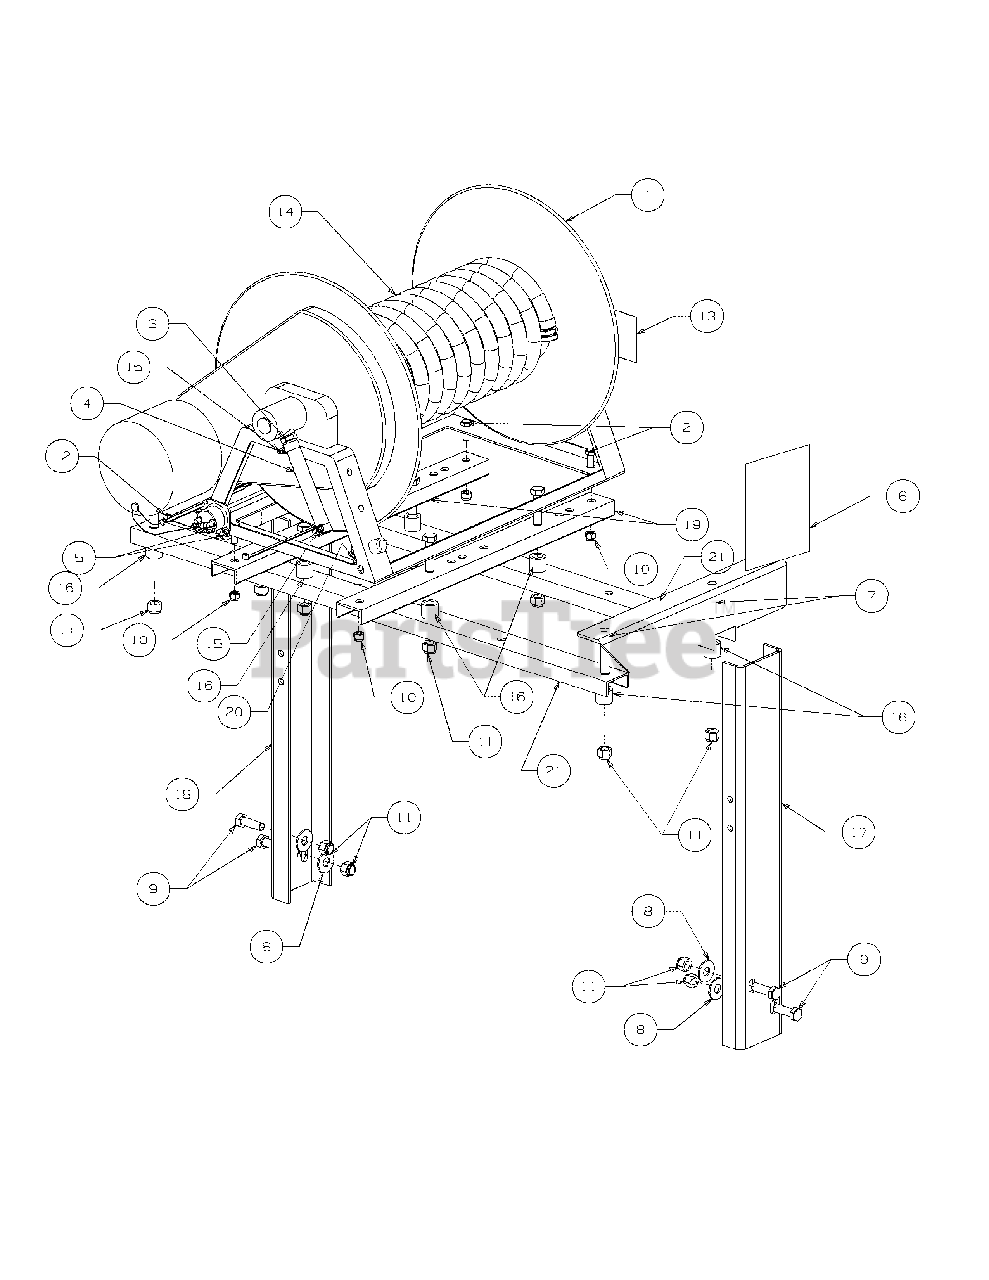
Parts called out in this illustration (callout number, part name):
2	Capscrew, 3/8-16 x 1
3	1/2 Hose Barb, 1/2 (M) NPT
4	1/2" Hose by the foot
5	Ring Terminal, 3/8"
6	Electric Wiring Kit
7	Cap Screw, 1/2-13 x 2 Hex Hd
8	Flat Washer, 1/2 USS
9	Cap Screw, 1/2-13 x 1-1/2 Hex Hd
10	Lock Nut, Nylon Insert, 3/8-16
11	Lock Nut, Nylon Insert, 1/2-13
12	Cable Tie
13	Decal, Maximum Hose Length
14	Hose Assembly, 800 PSI, 1/2" x 300'
15	Hose Clamp, 1/2, 7/8
16	Spacer, Cross Bar
17	Upright, Engine Side, Right
18	Upright, Pump Side, Left
19	Channel, Pick-up Mount
20	Wiring Harness
